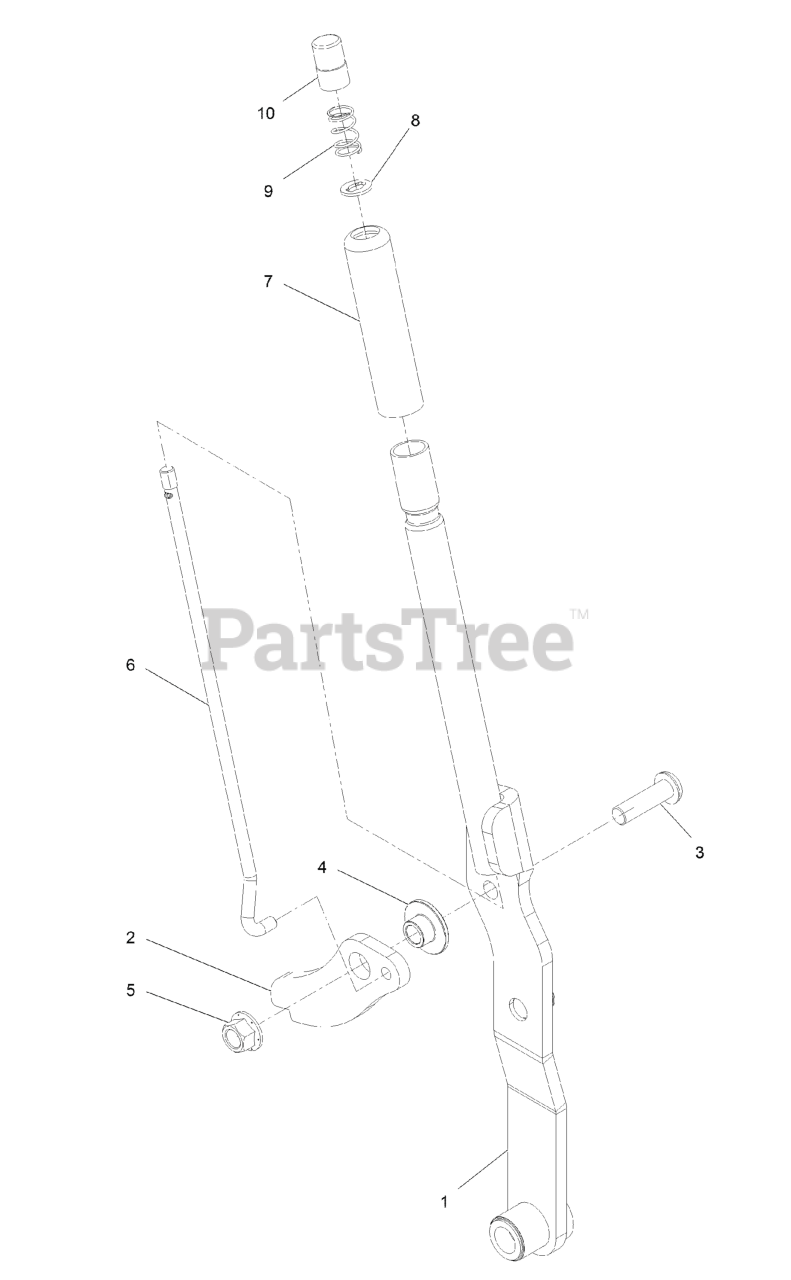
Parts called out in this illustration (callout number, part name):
1	ASM, HOC LEVER W/ BUSHINGS
2	ARM, TRANSPORT LOCK
3	SCREW-HSBH
5	Nut-Lock 1/2-13
6	LINC, HOC
8	WASHER-SPECIAL
9	SPRING-COMPRESSION
